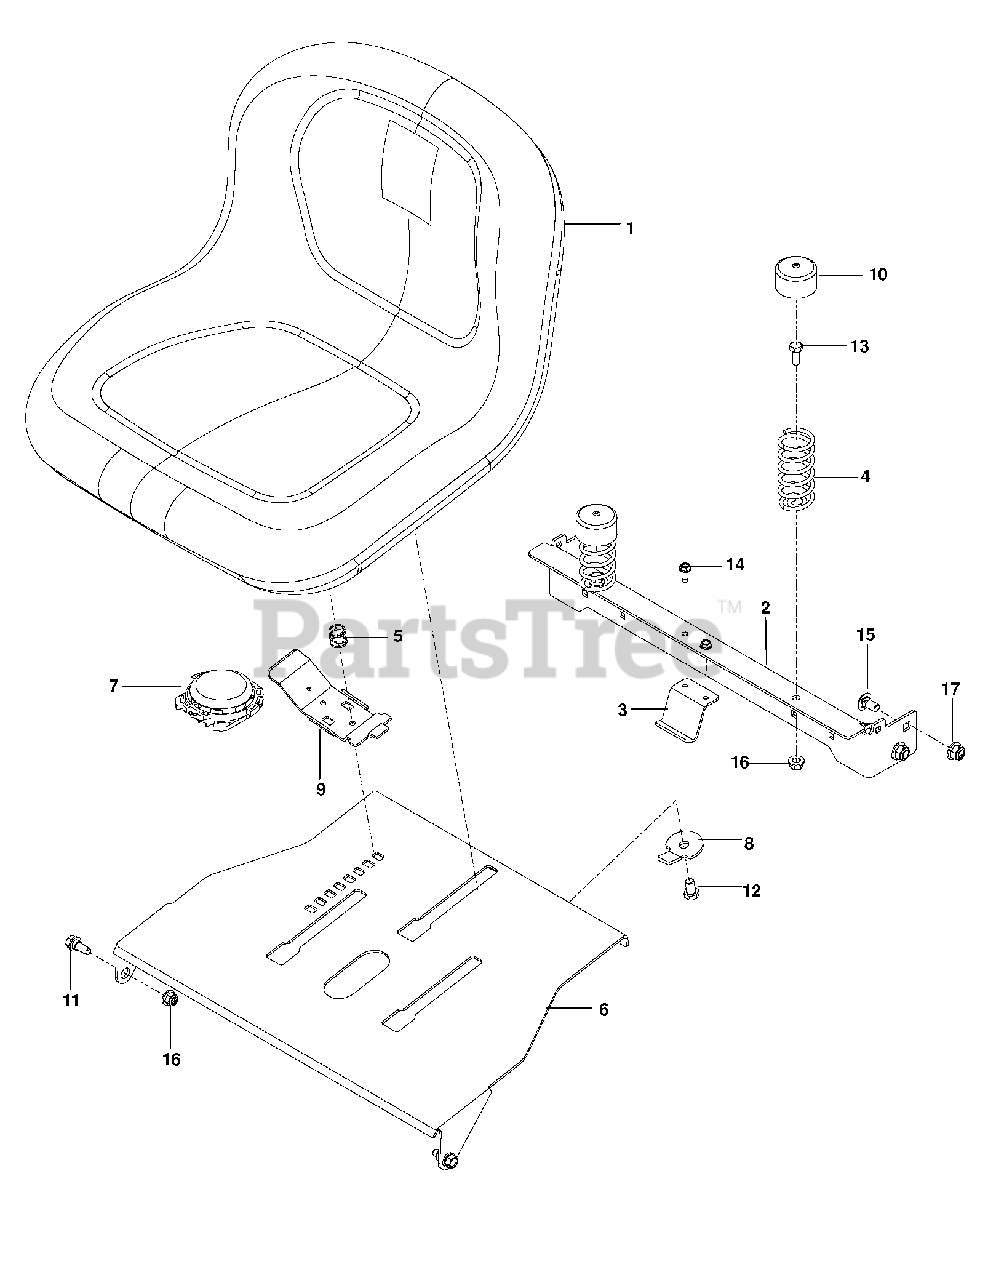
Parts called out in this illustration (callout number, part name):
1	SEAT.TG150.BLK.NLOGO.
2	SEAT SUPPORT, REAR, BLUE
3	HOLDING DEVICE, FUEL TANK, BLK
4	SEAT SPRING
5	SPRING.LATCH.SEAT.TEX
6	PLATE, SEAT, BLUE
7	SWITCH, SEAT N/C
8	STOP, SEAT, BLACK
9	HANDLE.SLIDE.SEAT.TEX.BLACK
10	SPRING CAP
11	BOLT, SHOULDER
12	HCS 3/8-16 X 5/8 GR 5 ZD
13	HCS 5/16C X 3/4
14	SCREW 1/4 X 5/8
15	RHSNB 3/8-16 X 3/4 GR5 ZD
16	5/16-18 NYLOC FLANGE NUT
17	NUT 3/8-16 HEX FLG NYLOC ZD
